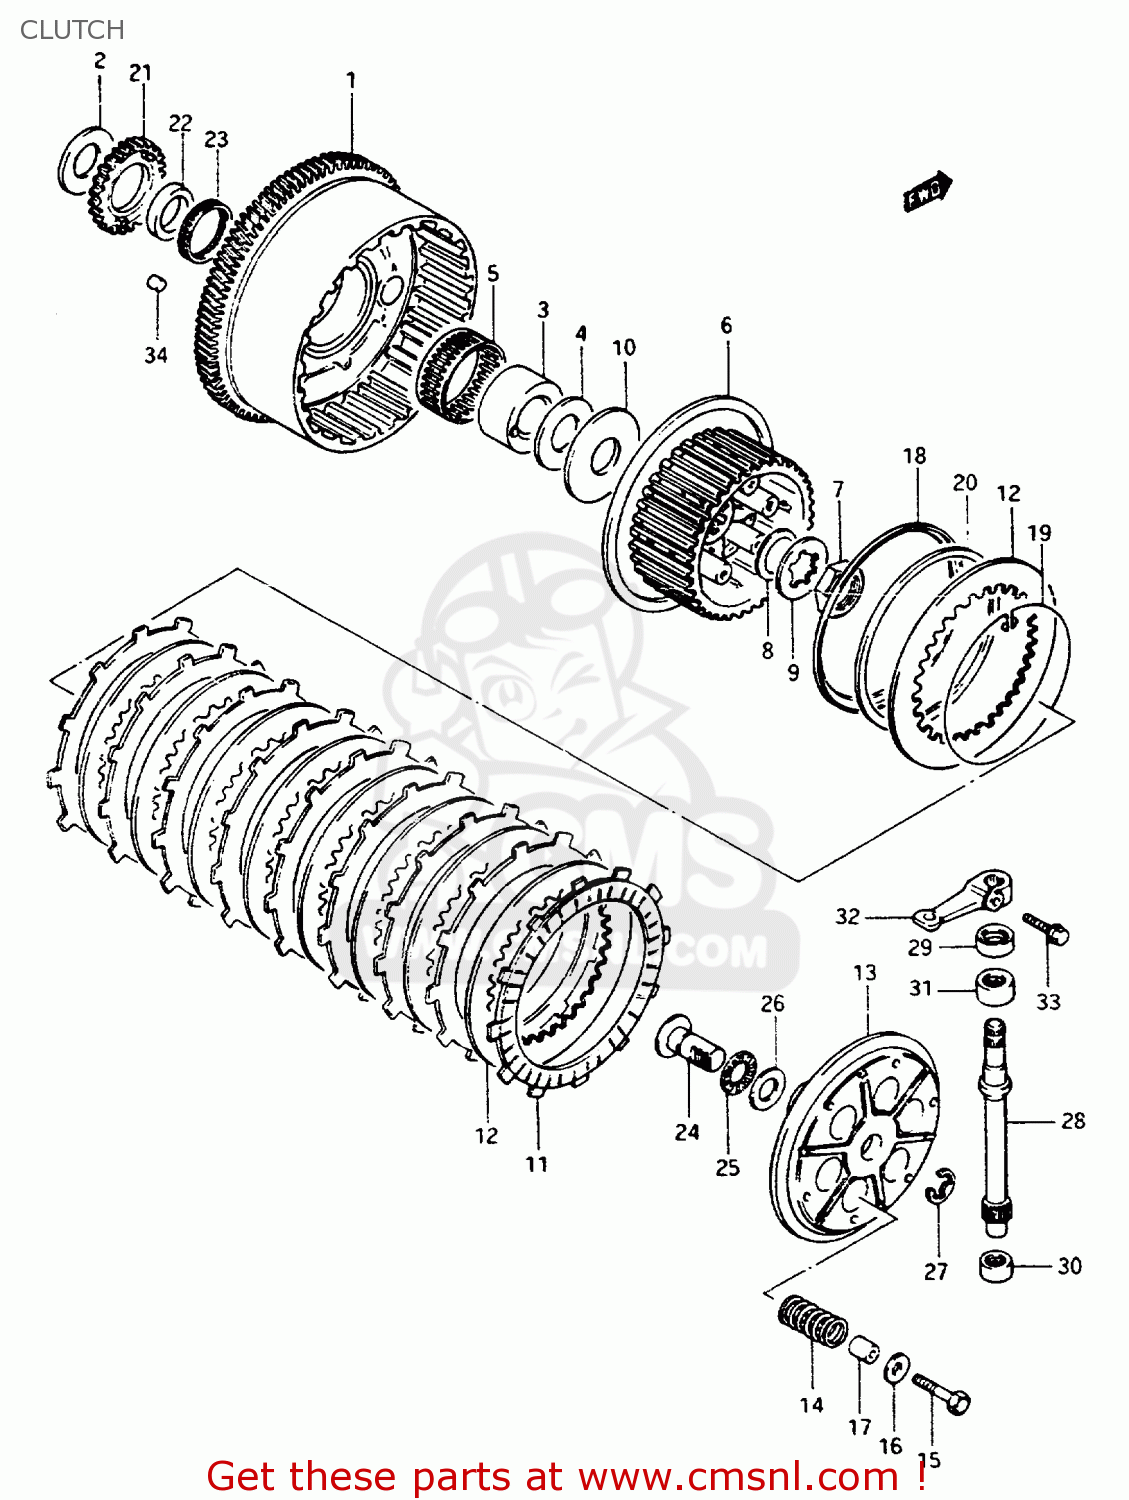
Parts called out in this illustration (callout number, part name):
1	GEAR ASSEMBLY,PRIMARY DRIVE
2	WASHER(25X50X2.5)
3	SPACER
4	SHIM(T:1.00)
5	BEARING(51X56X28)
6	HUB,CLUTCH SLEEVE
7	NUT
8	WASHER
9	WASHER,LOCK
10	WASHER(25X66X3.5)
11	PLATE,CLUTCH DRIVE (MCA)
12	PLATE,CLUTCH DRIVEN (NAS)
13	DISC,CLUTCH PRESSURE
14	SPRING
15	BOLT
16	WASHER
17	SPACER
18	SEAT,WAVE WASHER
19	RING,STOPPER
20	WASHER
21	GEAR,ENG OIL PUMP DRIVE(NT:34)
22	SPACER,OIL PUMP DRIVE GEAR
23	BEARING(36X40X10)
24	RACK,CLUTCH RELEASE
25	BEARING(15X28X2)
26	WASHER
27	E RING 12MM
28	PINION,CLUTCH RELEASE
29	OIL SEAL
30	BEARING(12X19X12)
31	BEARING(15X22X12)
32	ARM,CLUTCH RELEASE
33	BOLT (6X20)
34	CUSHION,PRIMARY DRIVEN GEAR
